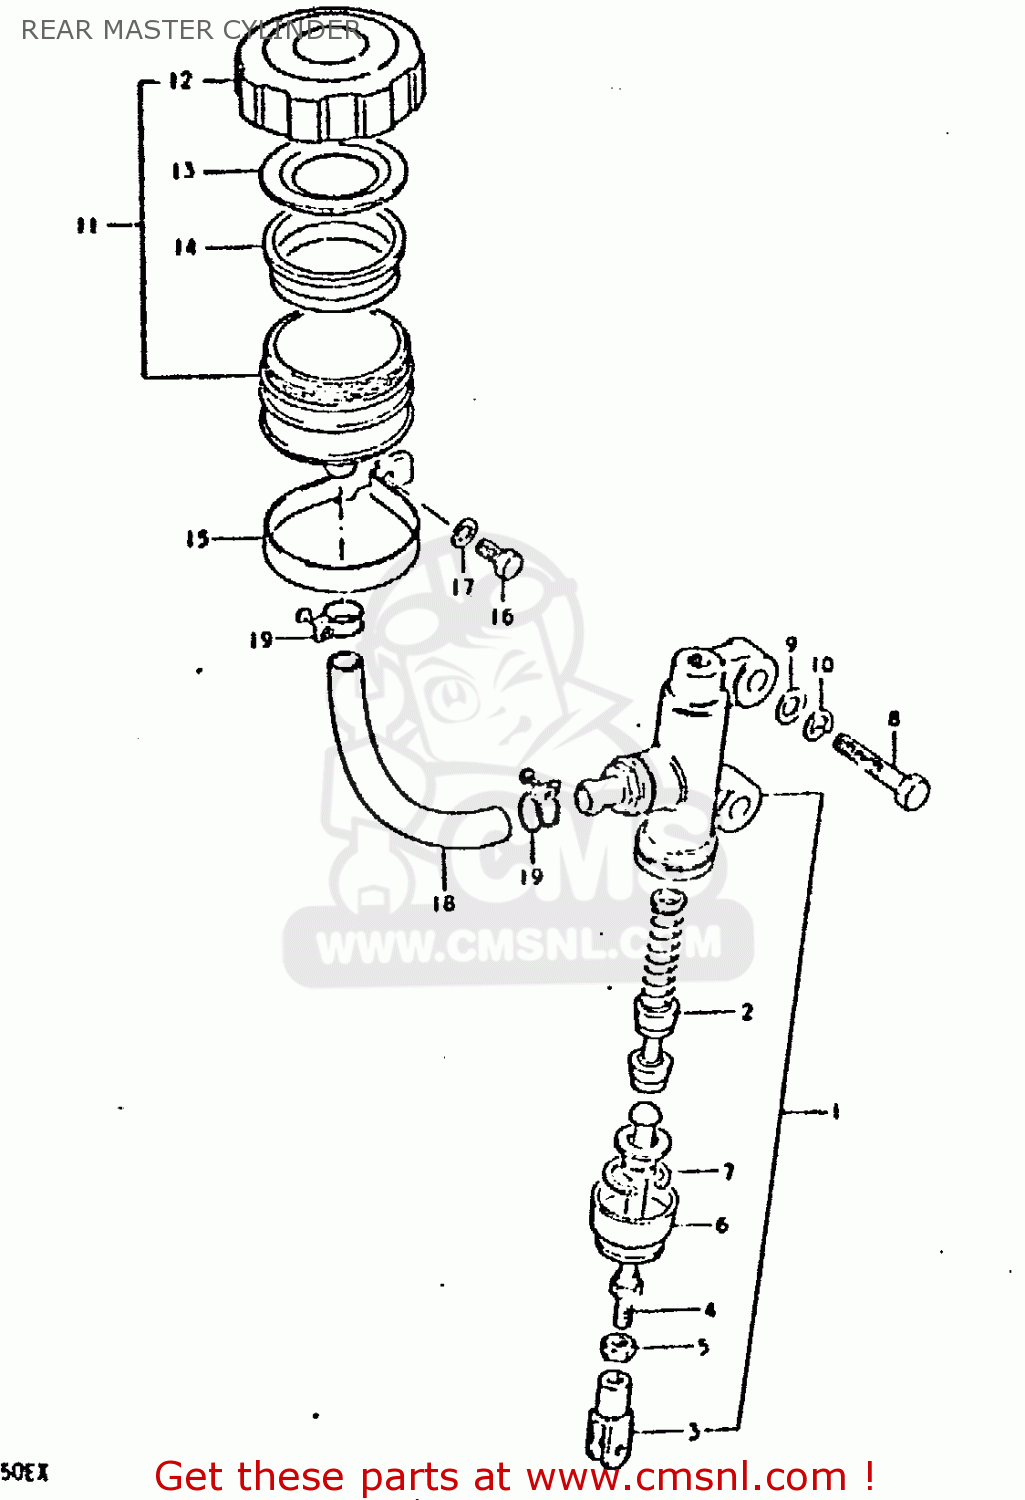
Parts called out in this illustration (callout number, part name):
1	CYLINDER ASSEMBLY,REAR MASTER
2	PISTON/CUP SET
3	YOKE
4	ROD,PUSH
5	NUT
6	BOOT
7	CIRCLIP
8	BOLT (8X30)
9	WASHER
10	LOCK WASHER
11	TANK ASSEMBLY,RESERVOIR
12	CAP
13	PLATE,DIAPHRAGM
14	DIAPHRAGM
15	CLAMP
16	BOLT, UPPER
17	LOCK WASHER
18	HOSE,RESERVOIR TANK
19	CLAMP
